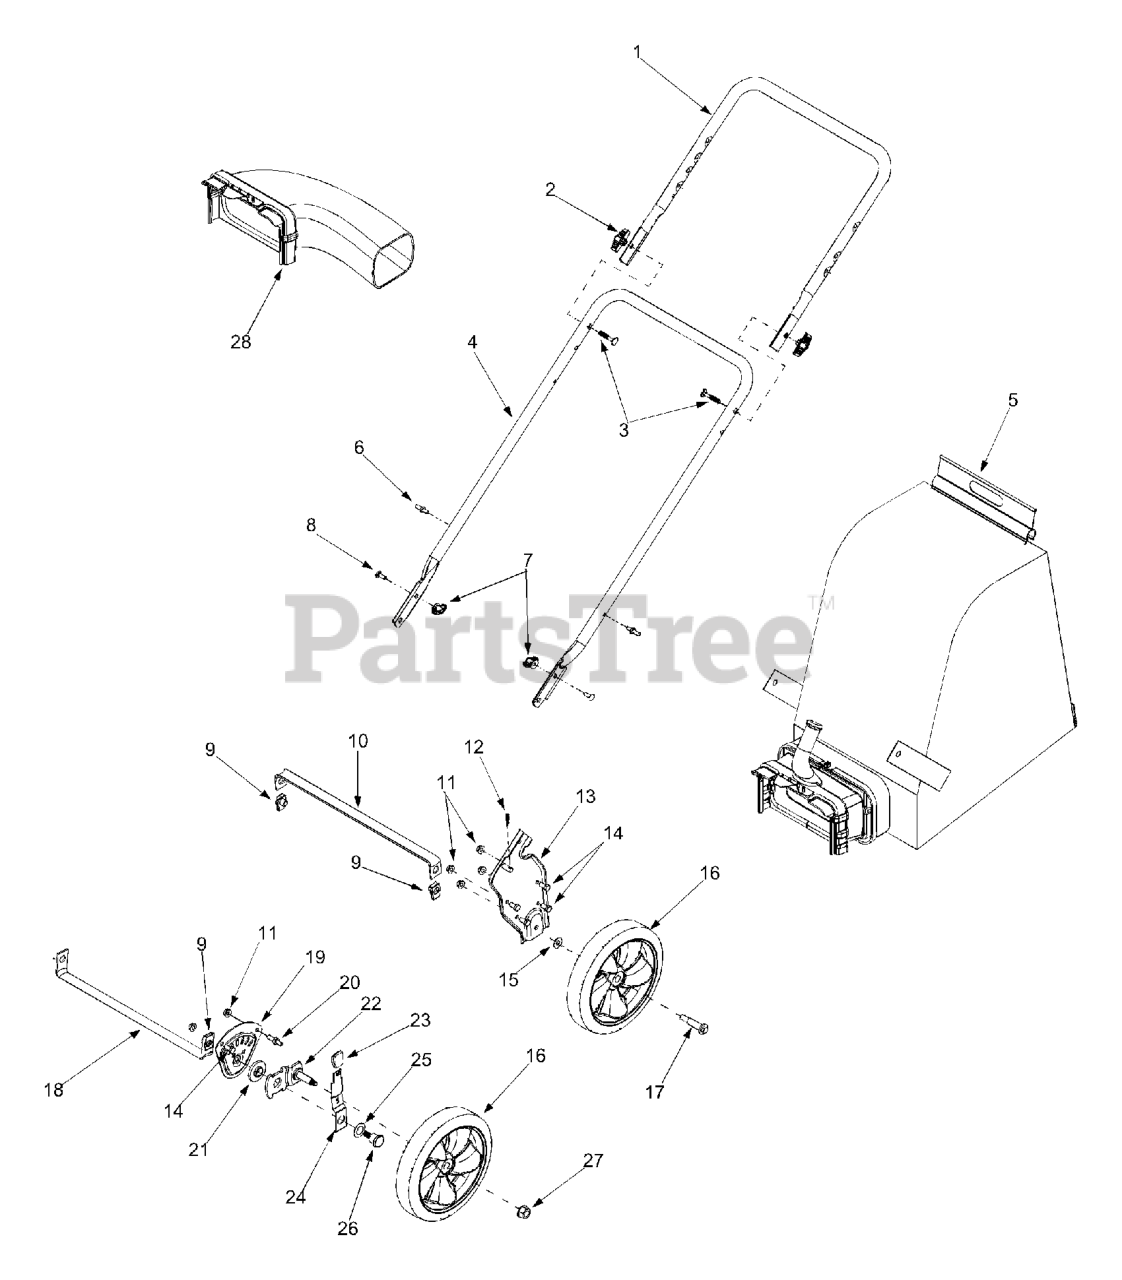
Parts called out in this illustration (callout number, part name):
1	Upper Handle
2	Handle Knob 5/16-18
3	Carriage Bolt
5	Bag Only
6	Studs
7	Wing Nut 1/4-20
8	Carriage Screw 1/4-20 x.75
9	Lock U-Clip Nut 3/8-16
12	Cotter Pin
14	Hex Cap Screw 5/16-18 x.625
15	Bell Washer.401 ID x.870 OD
16	Wheel 8 x 8.1
17	Shoulder Screw 3/8-16
18	Front Wheel Support Brace
19	Height Adjustment Bracket
20	Stud 5/16-18 .56 x .75
21	Height Adjustment Bearing
22	Pivot Arm Assembly
23	Height Adjustment Knob
24	Spring Lever
25	Bell Washer .760 ID x .25OD
26	Shoulder Screw .750 ID x .625 OD
27	Flange Lock Nut 3/8-16
28	Blower Chute Ass'y
